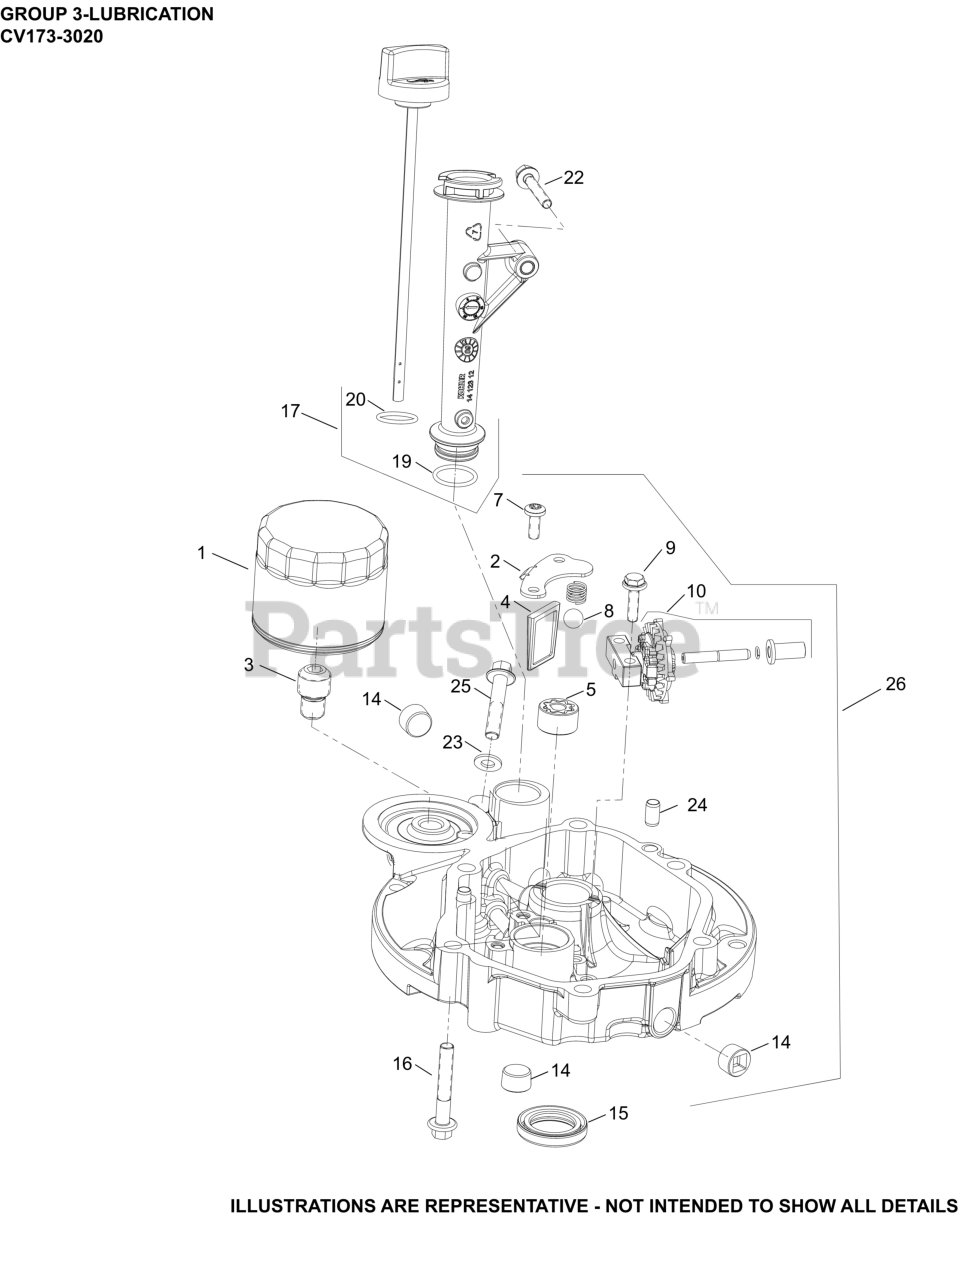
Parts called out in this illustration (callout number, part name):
1	FILTER, OIL
2	COVER, OIL PUMP SCREEN
3	NIPPLE, OIL FILTER
4	SCREEN, OIL
5	PUMP ASSEMBLY, OIL (GE-ROTOR)
7	SCREW, M6 X 16
8	BALL, STEEL COMPOSITE
9	SCREW, M6 X 22
10	GOVERNOR GEAR, ASSEMBLY
14	PLUG, PIPE (W/SEALANT)
16	SCREW, HEX FLANGE (M8)-USE 25 086 456-S
17	TUBE ASSEMBLY OIL FILL
19	O-RING, OIL FILL TUBE
20	O-RING (CAP)
22	SCREW, HEX FLANGE (M6)-(#25086435S)
23	WASHER, CLEAN OIL SCREW
24	PIN, DOWEL (8mm)
25	SCREW, CLOSURE PLATE
26	PAN, OIL ASSEMBLY (KIT)
